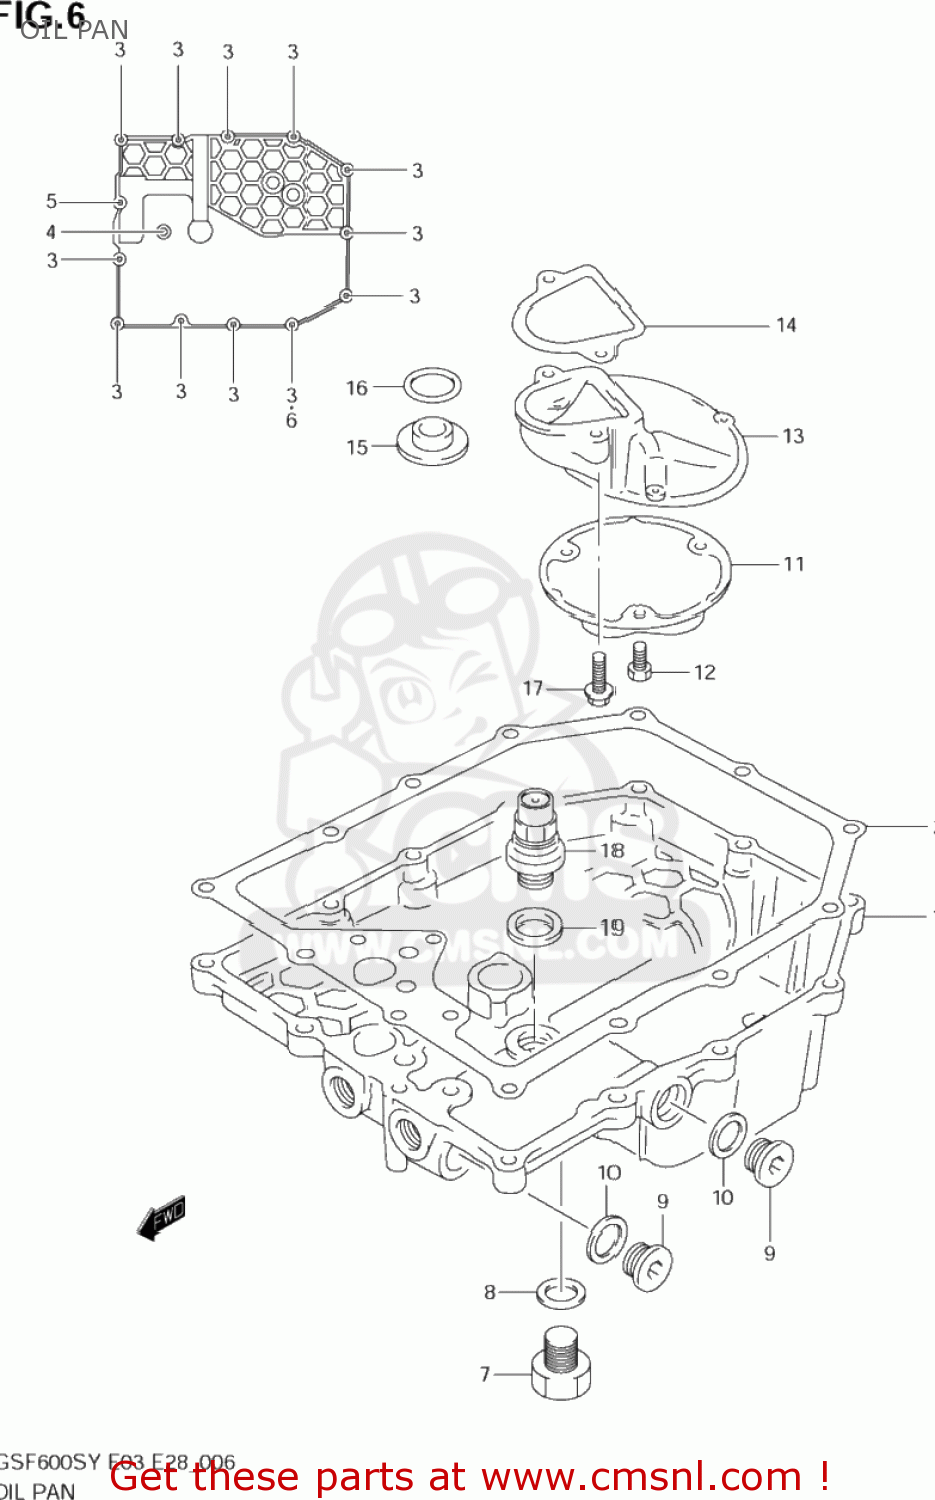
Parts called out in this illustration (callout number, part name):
1	PAN,OIL
2	GASKET,OIL PAN(ASB) (NAS)
3	BOLT
4	BOLT
5	BOLT
6	GASKET(5.8X13X1.2) (NAS)
7	PLUG
8	GASKET(13.8X18.8X4.8) (NAS)
9	PLUG,16X8
10	GASKET(16X22X2) (NAS)
11	STRAINER,ENGINE OIL
12	BOLT
13	PROTECTOR,OIL STRAINER
14	GASKET,OIL STRAINER PROTECTOR (NAS)
15	GASKET,OIL OUTLET (NAS)
16	O RING(D:3.2,ID:17.8)
17	BOLT
18	VALVE ASSEMBLY,OIL RELIEF
19	GASKET(16X22X2) (NAS)
